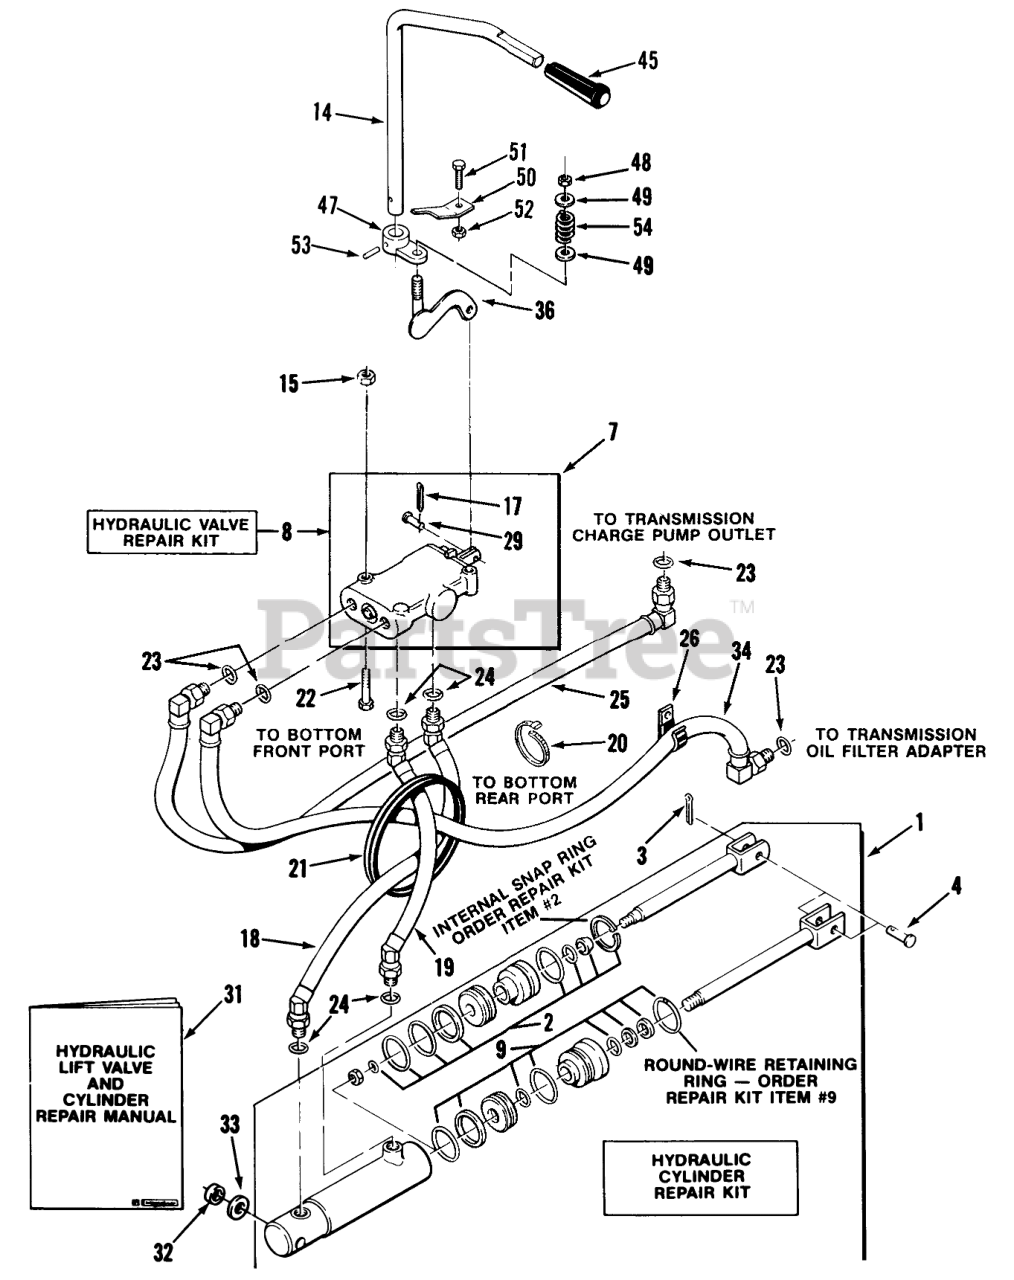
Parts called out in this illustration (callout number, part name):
1	ASS'Y-CYLINDER
2	S/A O-RING&GASKET AS
3	PIN-COTTER
4	CLEVIS PIN
7	ASS'Y-VALVE
8	S/A 110068 VALVE
9	S/A 108872 HYD CYL
14	ROD-LIFT CONTROL
15	Nut
17	Cotter Pin
18	Hose ASM-Hydraulic
19	Hose ASM-Hydraulic
20	PLASTIC TIE
21	GROMMET
22	Bolt 1/4-20 x 2
23	0-Ring
24	O RING
25	ASSY HOSE HYDRAULIC
26	CLIP
29	Pin
31	Repair Manual
32	Spacer
33	WASHER
34	ASSY HYD HOSE
36	WLDMT-LIFT BAR
45	KNOB-HYDRAULIC LIFT
47	ARM-CONTROL
48	NUT-LOCK, NI
49	WASHER 5/16 SAE
50	BRACKET-CONTROL R B
51	Bolt
52	Nut
53	SPIROL PIN 7/32X7/8
54	SPRING
